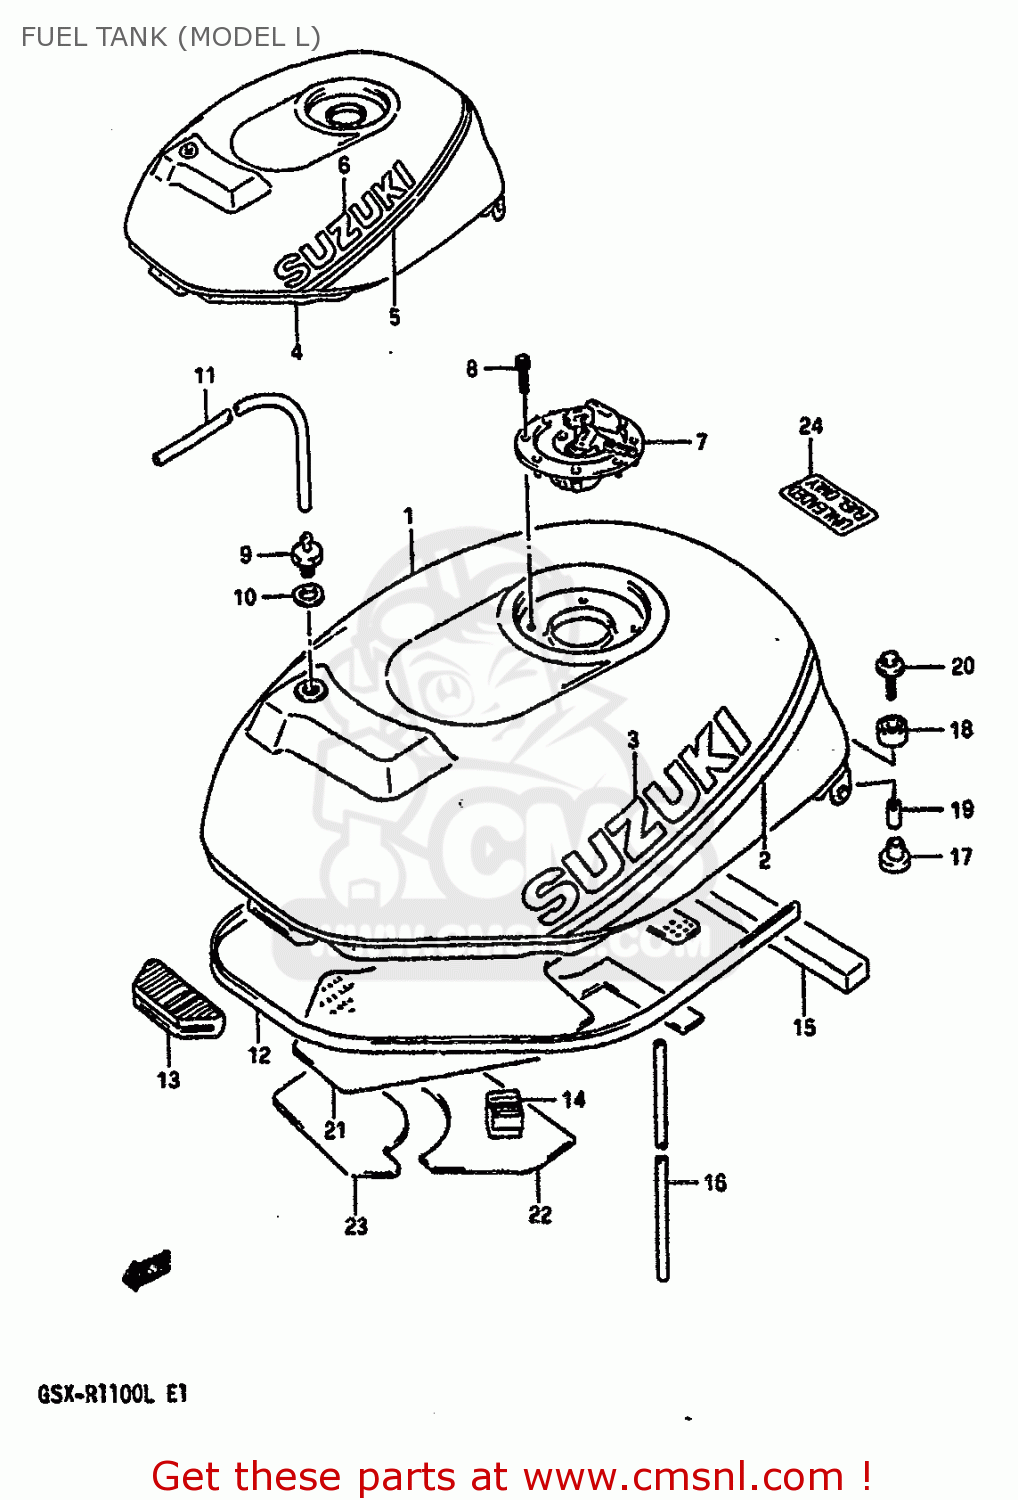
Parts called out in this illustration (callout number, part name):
1	TANK ASSY,FUEL
2	TAPE,FUEL TANK
3	EMBLEM,FUEL TANK
4	TANK ASSY,FUEL
5	TAPE,FUEL TANK
6	EMBLEM,FUEL TANK
7	CAP SET,FUEL TANK
8	BOLT(5X20)
9	PLUG,FUEL TANK BREATHER
10	GASKET(12.5X20X2.5) (NAS)
11	HOSE(5X8.2X600)
12	MOLDING,FUEL TANK
13	CUSHION,FUEL TANK FR
14	CUSHION,FUEL TANK SIDE
15	CUSHION, AIR SEAL
16	HOSE
17	CUSHION
18	CUSHION
19	SPACER
20	BOLT(6X35)
21	HEAT SHIELD,FUEL TANK
22	HEAT SHIELD,FUEL TANK IN
23	HEAT SHIELD,FUEL TANK IN
24	LABEL,FUEL CAUTION
27	COVER,FRONT,LEFT
28	BOLT
29	LABEL,FUEL CAUTION
